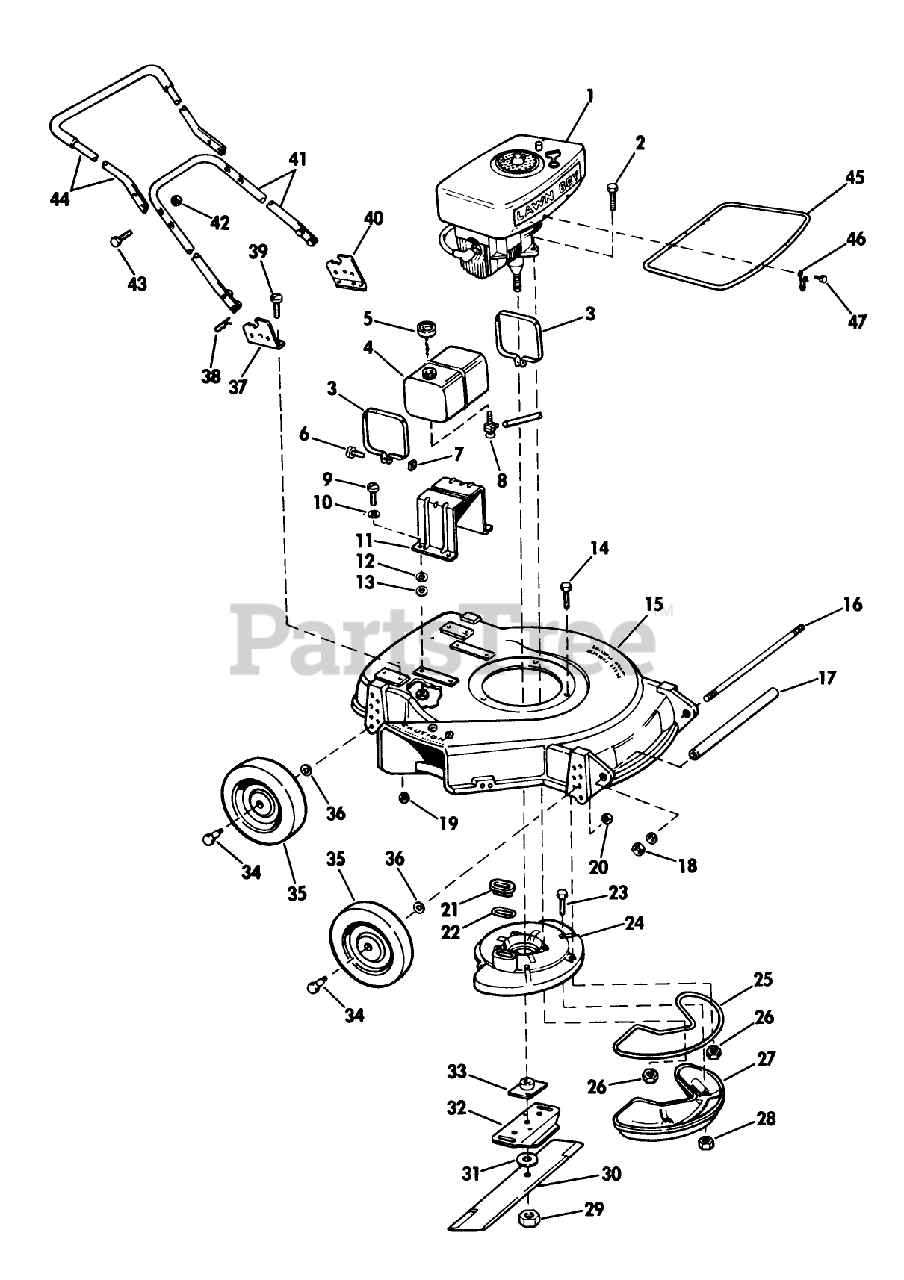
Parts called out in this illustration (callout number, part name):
8	VALVE&SCREEN SM
9	BOLT PIONEER
18	LOCKNUT
22	GASKET S
28	LOCKNUT E
29	NUT-BLADE
33	PLATE AND COLLAR ASM
36	WASHER WROUGHT
39	SCREW S
